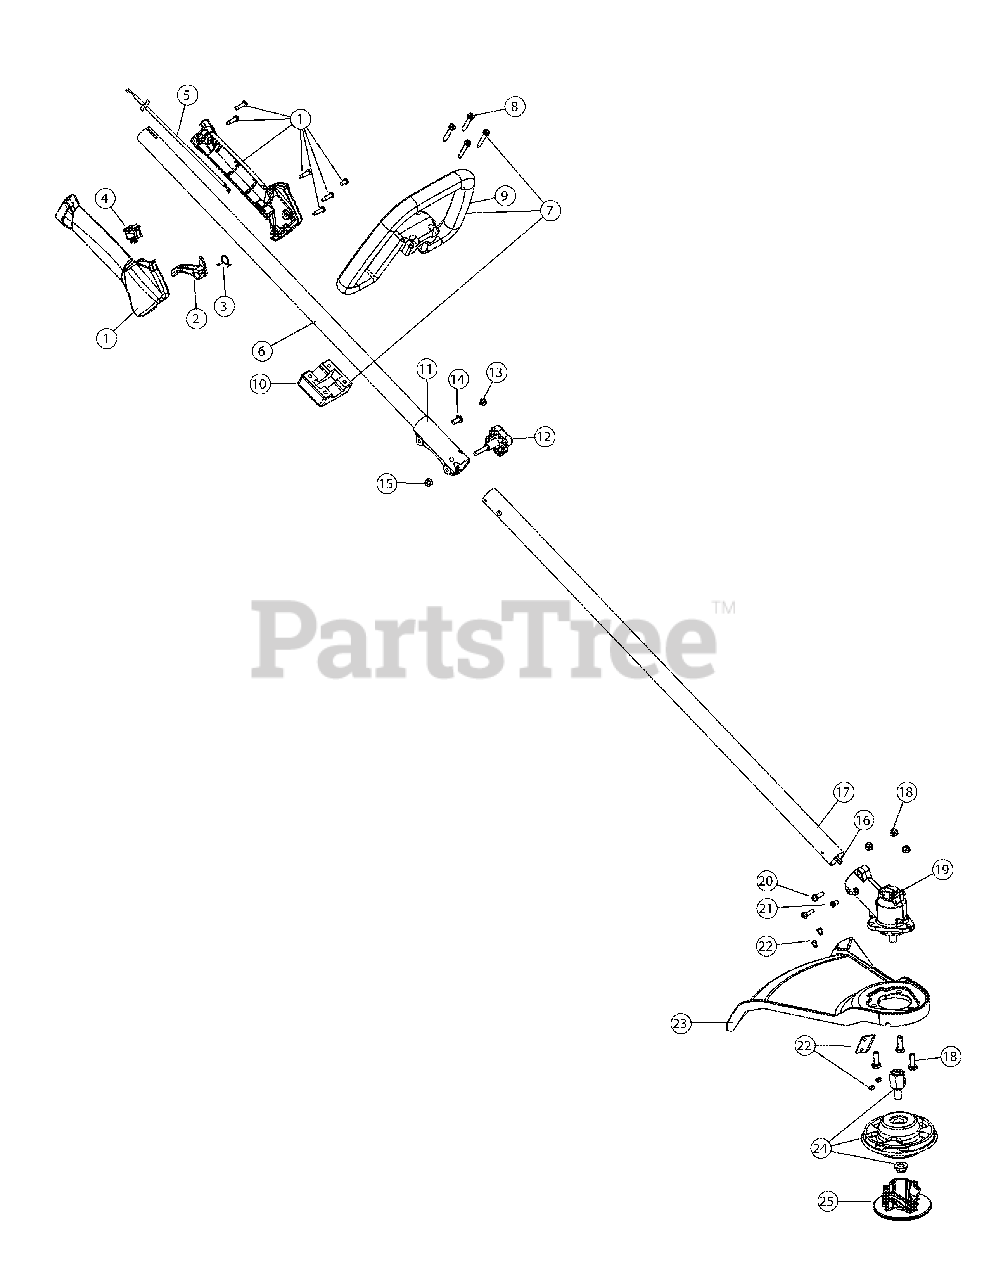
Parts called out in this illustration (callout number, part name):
1	Throttle Housing Assembly
2	Throttle Trigger
3	Throttle Trigger Spring
4	Switch Assembly
5	Throttle Cable Assembly
6	Upper Shaft assembly
7	Deluxe D-Handle Assembly
9	D-Handle
10	D-Handle Base
11	Split Boom Coupler
12	Adjustment Knob
15	Nut
16	Lower Flexible Drive Shaft
17	Lower Shaft Housing
18	Shield Mount Screw Assembly
19	Gearbox Assembly
20	Gearbox Screw
21	Anti-Rotation Screw
22	Blade Assembly
23	Shield Assembly
24	Cutting Head Assembly
25	Cutting Head Cap
